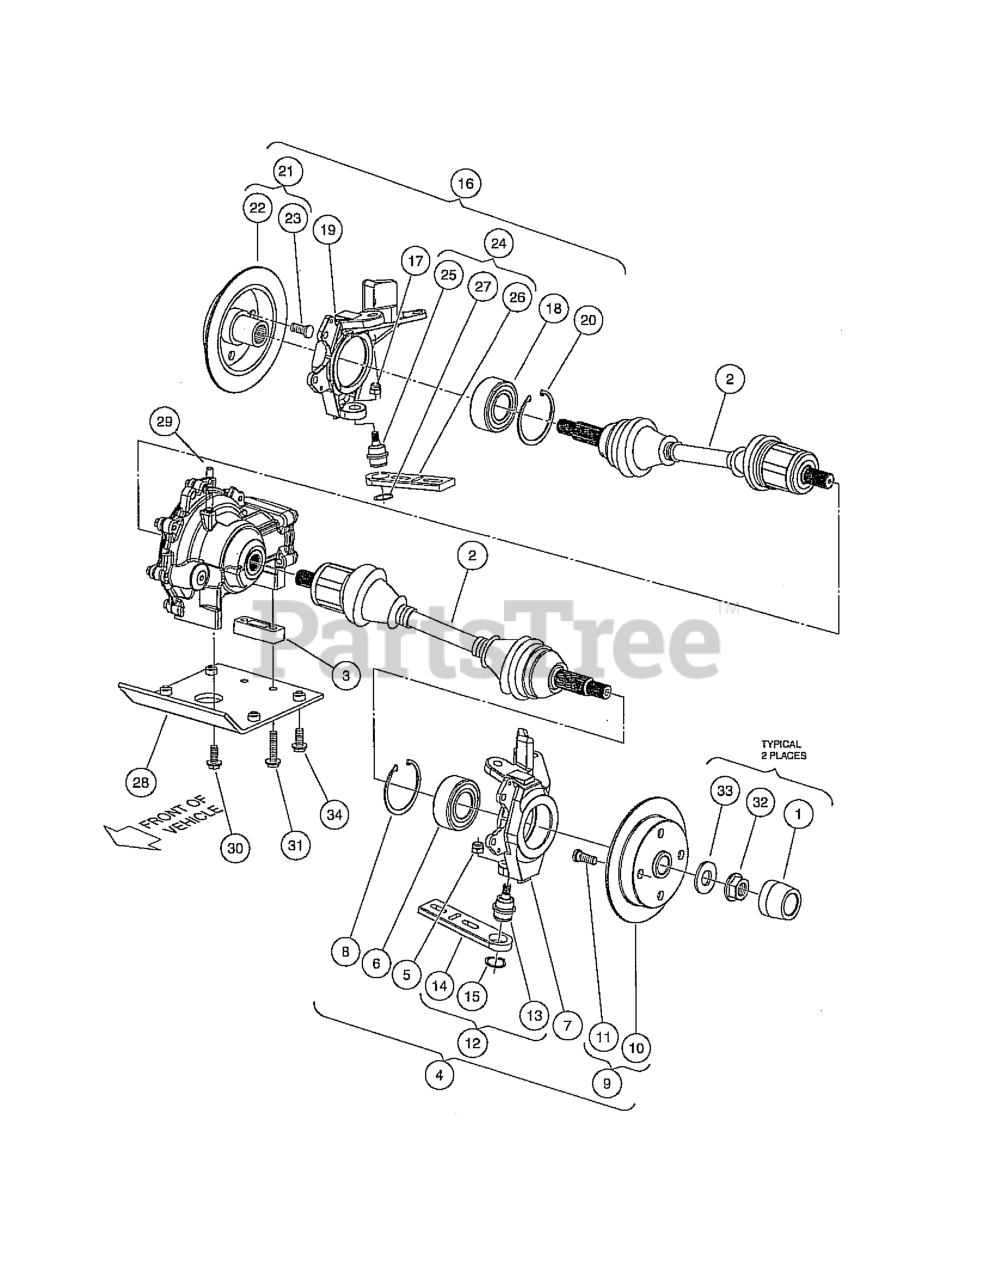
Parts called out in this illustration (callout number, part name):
1	CENTER CAP, RUBBER
2	HALF SHAFT
3	SPACER BLOCK, DIFF
4	UPRIGHT SUB ASSEMBLY LH
5	LOCKNUT, M12-1.25 NYLON
6	BEARING, 52082RS
8	INT RETAINING RING, 80MM BORE
9	ASSY, ROTOR, BRAKE, FRONT
12	ASM, ADJUSTER, SLIDE
13	BALL JOINT
14	SLIDE, ADJUSTER
15	RING, RETAINING, EXT, 1-1/4"
16	UPRIGHT SUB ASSEMBLY RH
17	LOCKNUT, M12-1.25 NYLON
18	BEARING, 52082RS
20	INT RETAINING RING, 80MM BORE
21	ASSY, ROTOR, BRAKE, FRONT
24	ASM, ADJUSTER, SLIDE
25	BALL JOINT
26	SLIDE, ADJUSTER
27	RING, RETAINING, EXT, 1-1/4"
28	MOUNT, DIFF PLATE ASM
29	HOSE, VENT, FRONT DIFF
30	BOLT FLG, 3/8-16X1.0 LOCTITE
31	BOLT FLG,3/8-16X1.500 LOCTITE
32	NUT FLG, M22 X 1.5 MECH DEF
33	WASHER HARD, M22
34	BOLT, FLANGE, M10 X 1.5 X 25
